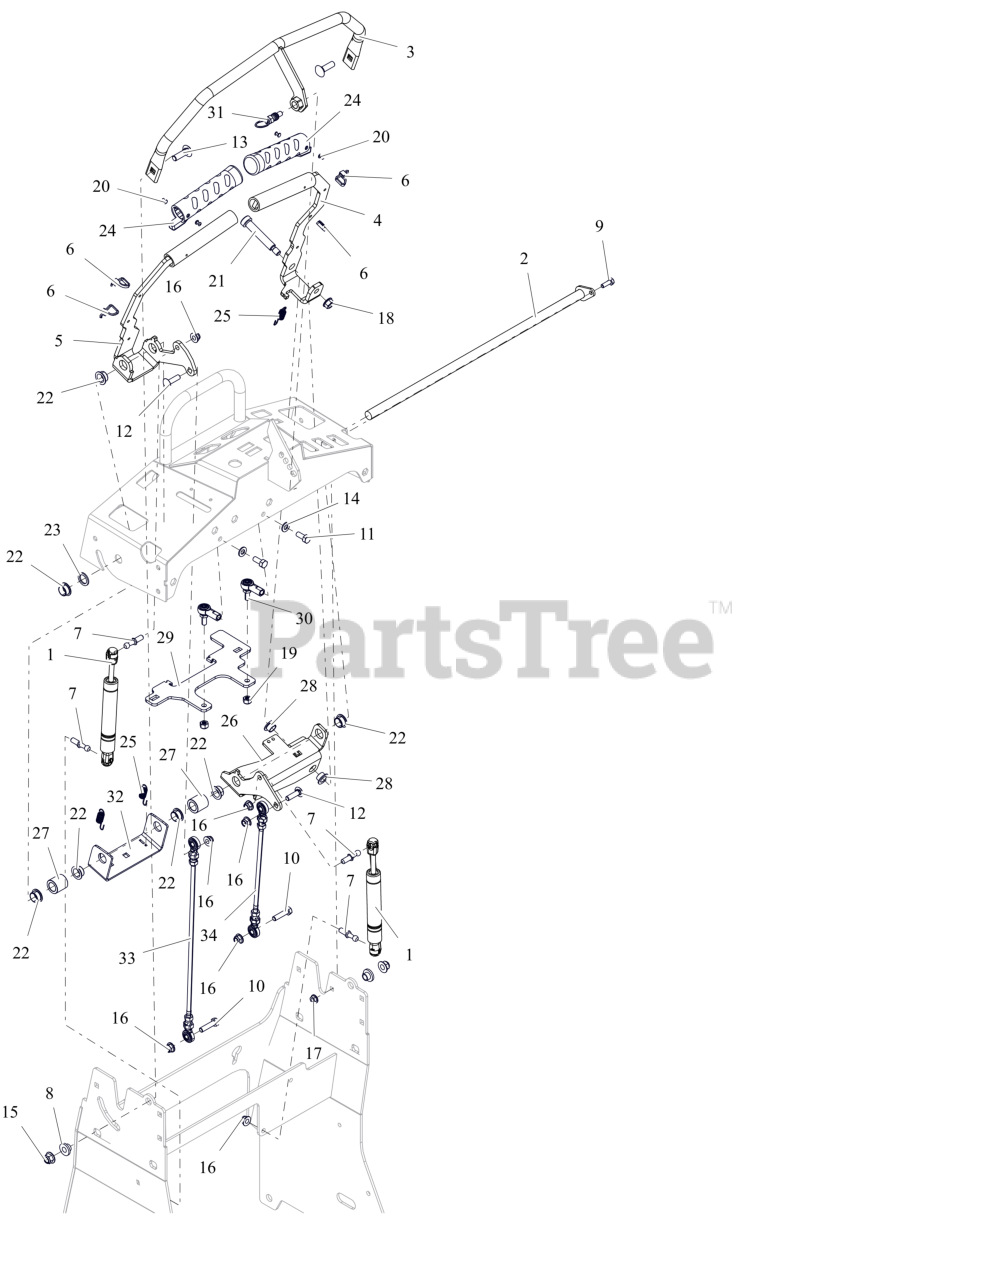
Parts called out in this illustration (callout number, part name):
1	DAMPER, CONTROL
2	PIVOT- ROD FLAG WLDMT
3	WLDMT- FWD SPEED BAR
4	WLDMT- CONTROL LH HANDLE
5	WLDMT- CONTROL RH HANDLE
6	TIE WRAP
7	STUD-BALL-THREADED
8	BSHG-FLG .385X.500X.875X.406
9	BLT, HEX .25-20X.75 G5 ZCC
10	BLT, HEX .31-18X1.25 G5 ZCC
11	BLT, HEX .31-24X.750 G5 ZCC
12	BLT, RHSSN .31-18X1.125 G5 ZCC
13	BLT, RHSN .38-16X1.25 G5 ZCC
14	WSHR,FLT .344X.688X.065 ZCC
15	NUT,NYL-FLG .38-16 GF ZCC
16	NUT,LK-NYL-FLG .31-18 G5ZC120
17	NUT-LK-CTR-FLG .25-20 ZC120
18	NUT-LK-CTR-FLG .375-16 GF ZCC
19	NUT- HEX NYLOCK 5/16-24
20	RVT-POP #44 .125X.188-25 STLZC
21	BLT-SHLDR 0.5 SH- .38-16X2.5
22	BUSHING- PLASTIC 5/8"
23	WASHER-FLAT-STL, METRIC M17X24X2
24	GRIP, HANDLE - HEATED
25	SPRING, EXT. .043X.438X1.64
26	PLATE- CONTROL LH HANDLE PIVOT
27	SPCR- PLASTIC LDPE
28	BUSHING- FLANGED PLASTIC
29	PLATE- BRAKE INTERLOCK
30	BALL- STUD ASSY 5/16-24
31	SPRG- LOCK PIN 1/2-13
32	PLATE- BRAKE CAM
33	LINKAGE- CONTROLS-5/16 -15.64"
34	LINKAGE- CONTROLS 5/16 -10.00"
